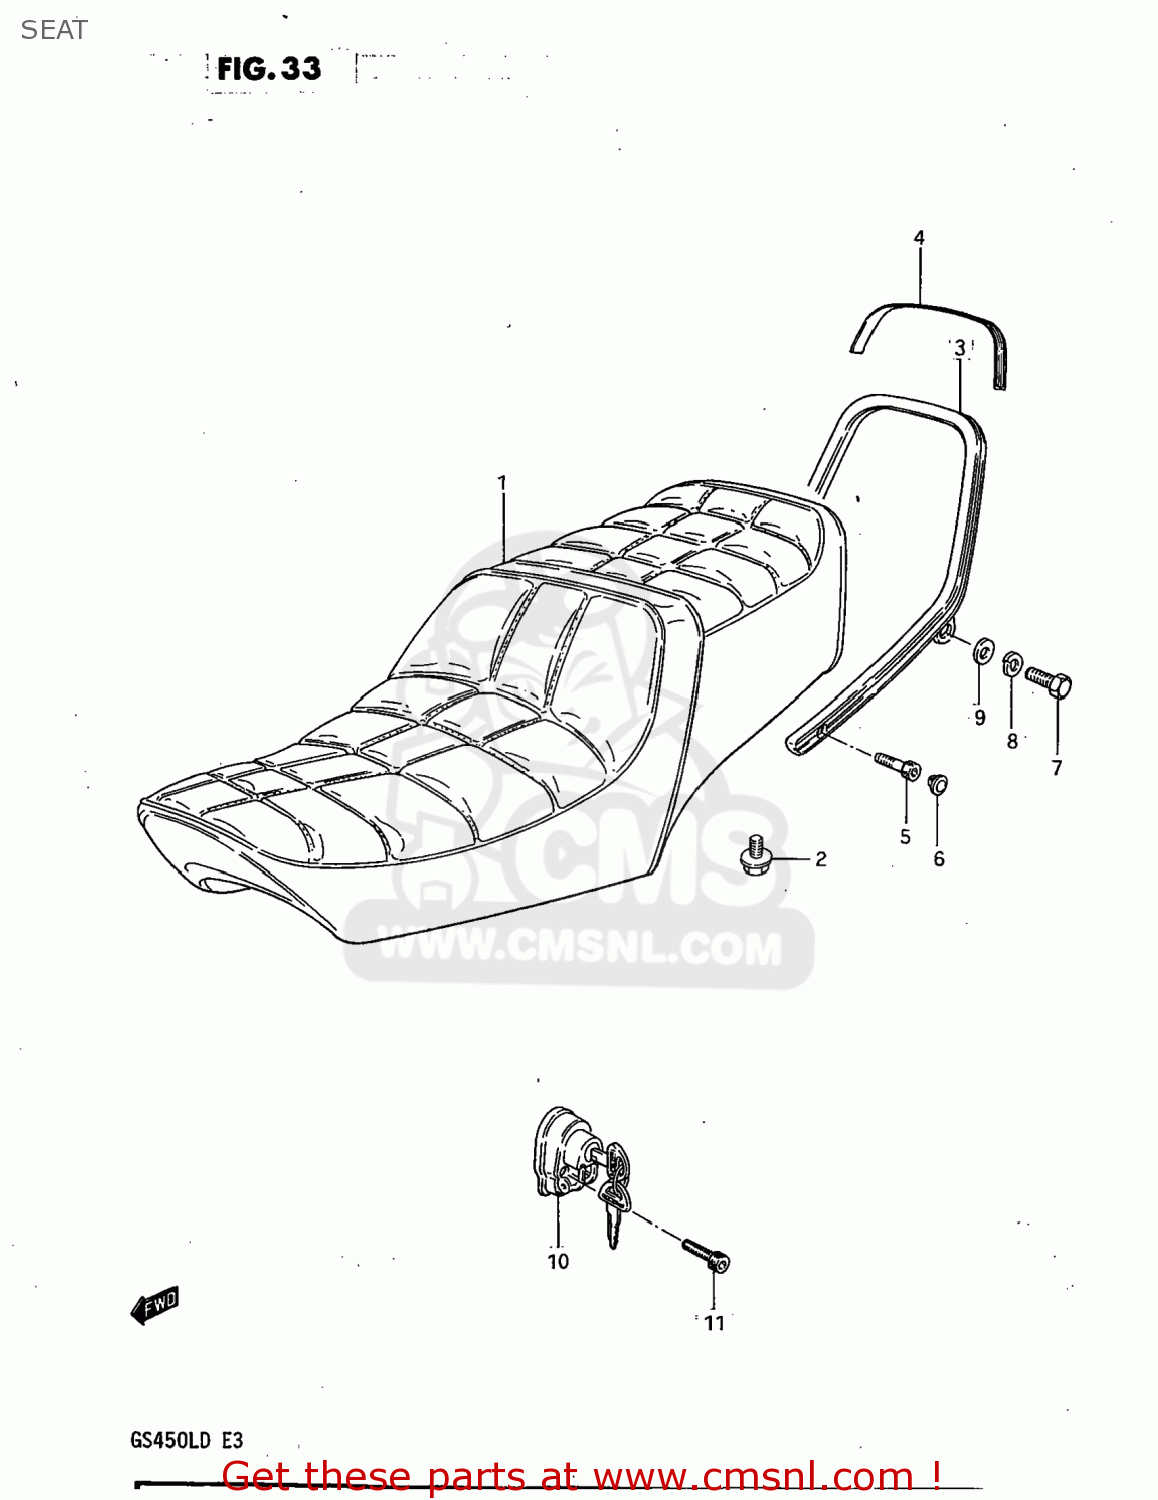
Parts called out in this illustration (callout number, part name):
1	SEAT ASSEMBLY
2	BOLT
3	HANDLE,PILLION RIDER
4	RUBBER,PILLION RIDER HANDLE
5	BOLT
6	CAP(OD:14.5)
7	BOLT
8	LOCK WASHER
9	WASHER
10	LOCK ASSY,HELMET
11	BOLT 5X25
